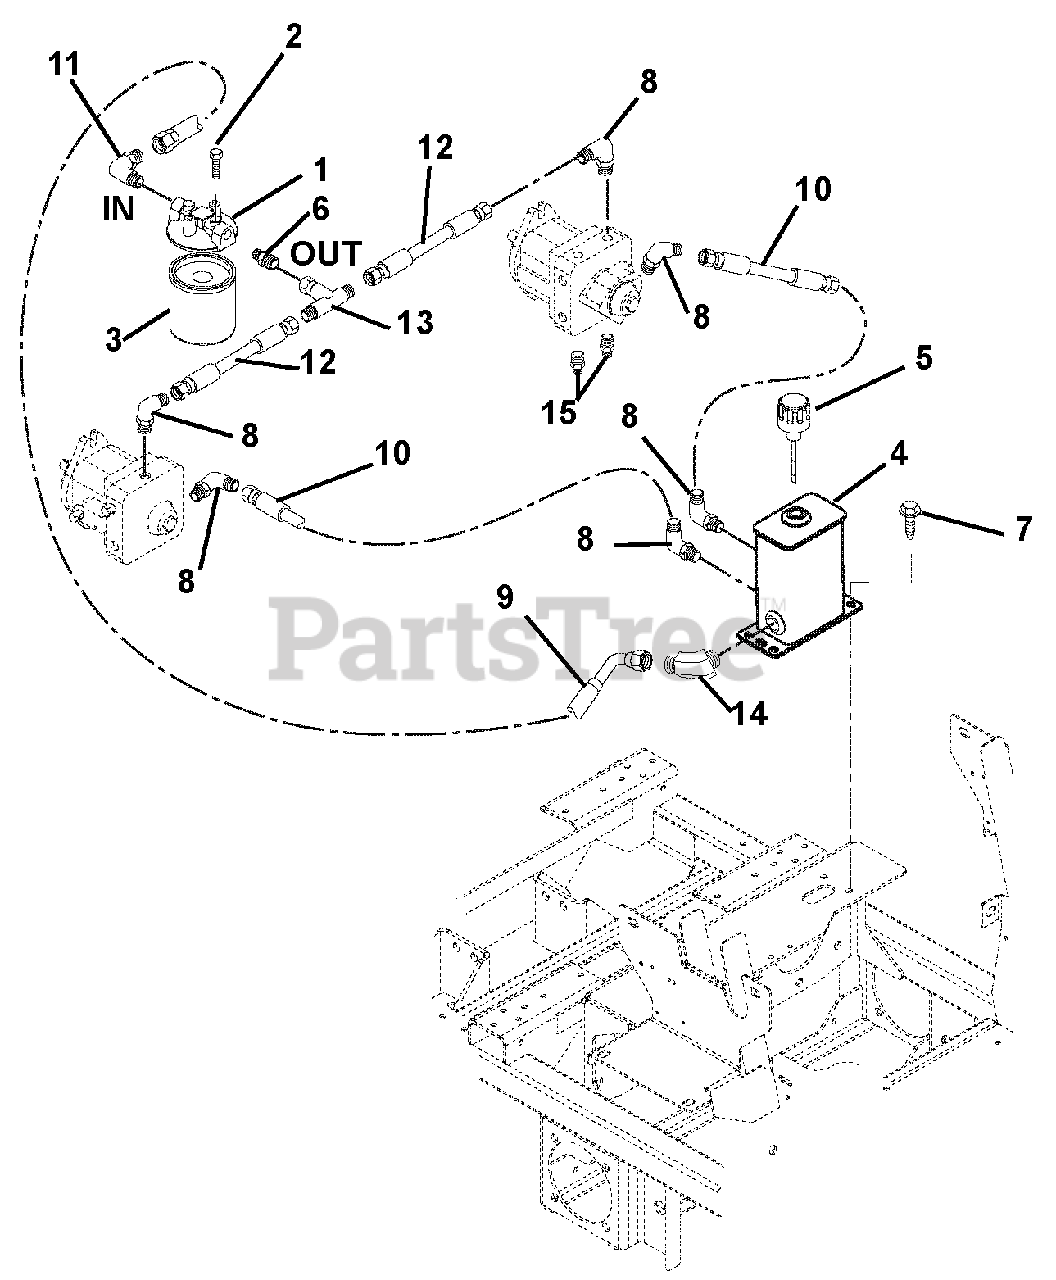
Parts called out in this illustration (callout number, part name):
1	FILTER HOUSING ZINGA ZAF11250
2	BLT-HEX .25-20X.50 GR5 EPOXY
3	FILTER ELEMENT, ZINGA AE-25
4	WMT, HYDRAULIC TANK
5	BREATHER, DIPSTICK
6	FTG.HYD STR.M8O-M12O (F5OLO-S)
7	@SCR-TAP .38-16X.75 HWH TR YWZ
8	FTG. HYD. 90 EL M8F-M8O
9	HOSE, HYD. .50-19-0K F8F0-F8F9
10	HOSE,HYD..50-10-0K FO8J0-FO8JO
11	FTG. HYD 90 EL M8O-M12O
12	HOSE,HYD. .50-5-0K FO8J0-FO8J0
13	FTG.HYD TEE M8O-F8O-F8O
14	FTG,HYD 45DEG M8F-M80
15	FITTING, HYD (4 F5OLO)
